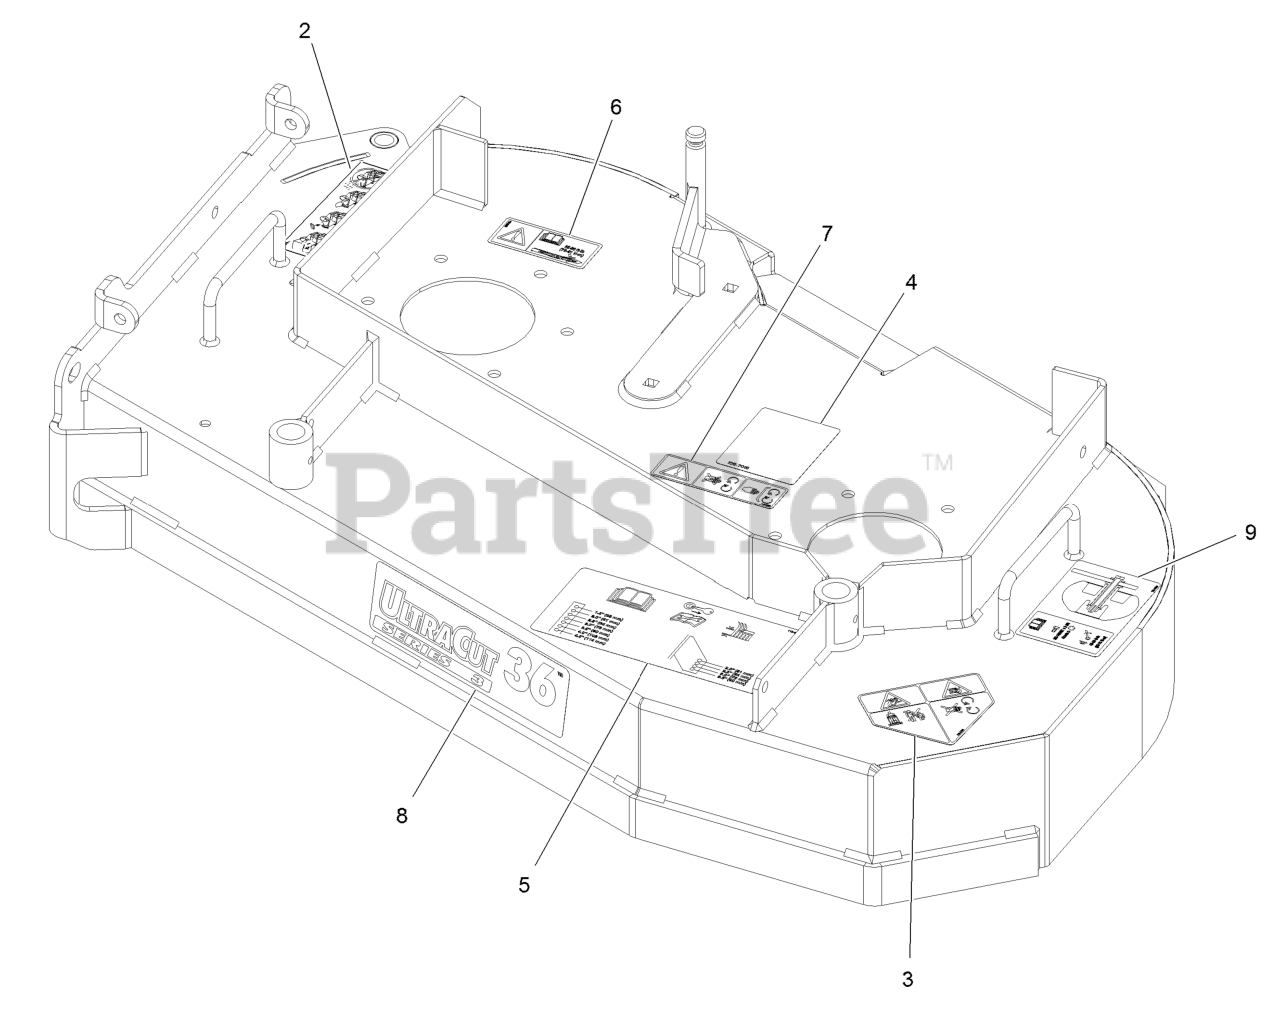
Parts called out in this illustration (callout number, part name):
2	DECAL-WARNING, BAGGER
3	DECAL-DANGER
4	DECAL-ROUTING, BELT
5	DECAL-ANTI-SCALP
6	DECAL-BOLT TORQUE
7	DECAL-COVER, MISSING
8	DECAL-ULTRACUT 36 SERIES
9	DECAL-ROLLER MOUNTING
